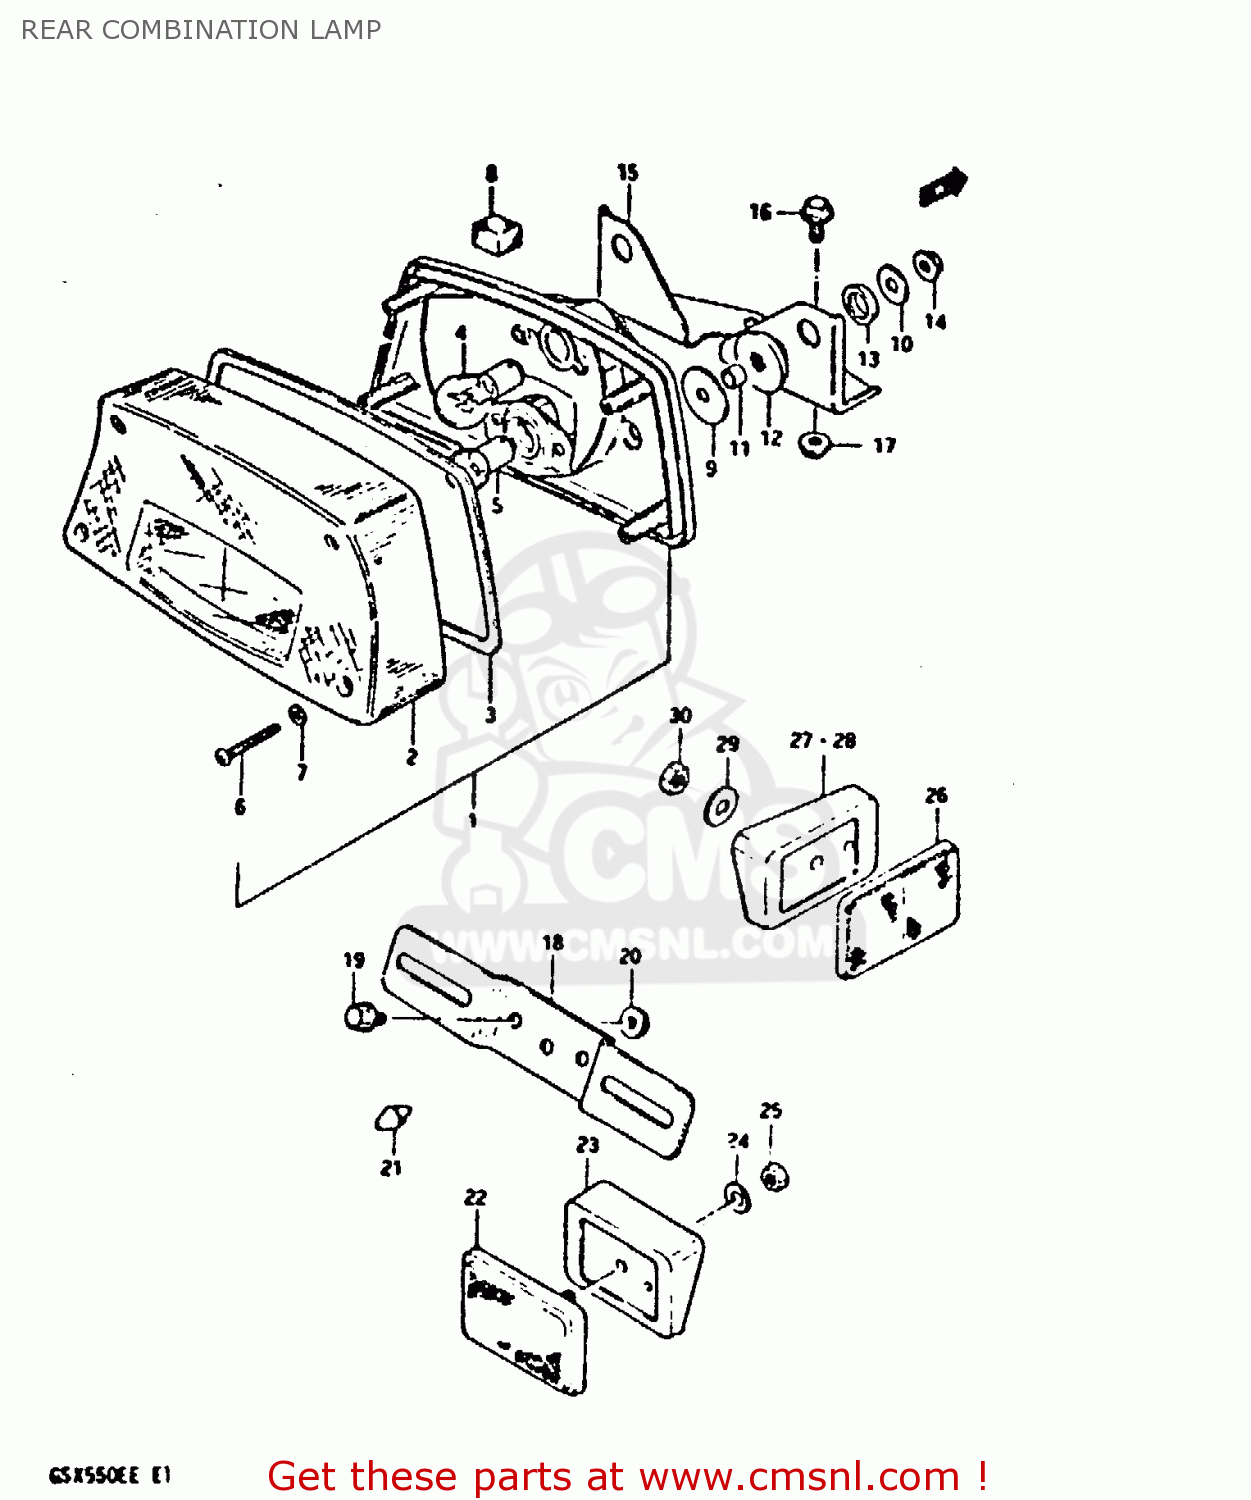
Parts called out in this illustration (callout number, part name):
1	LAMP ASSY, REAR COMBINATION
2	LENS
3	GASKET
4	BULB(12V21/5W)
5	BULB
6	SCREW ,4X25
7	GASKET (NAS)
8	CUSHION,REAR COMBINATION LAMP
9	WASHER(6.5X30X1.2)
10	WASHER(6,5X22X1.6)
11	SPACER (6.8X10X11.5)
12	CUSHION
13	CUSHION
14	NUT
15	BRACKET,REAR COMBINATION LAMP
16	BOLT
17	NUT
18	PLATE,RR LICENSE
19	BOLT 6X12
20	NUT
21	CUSHION
